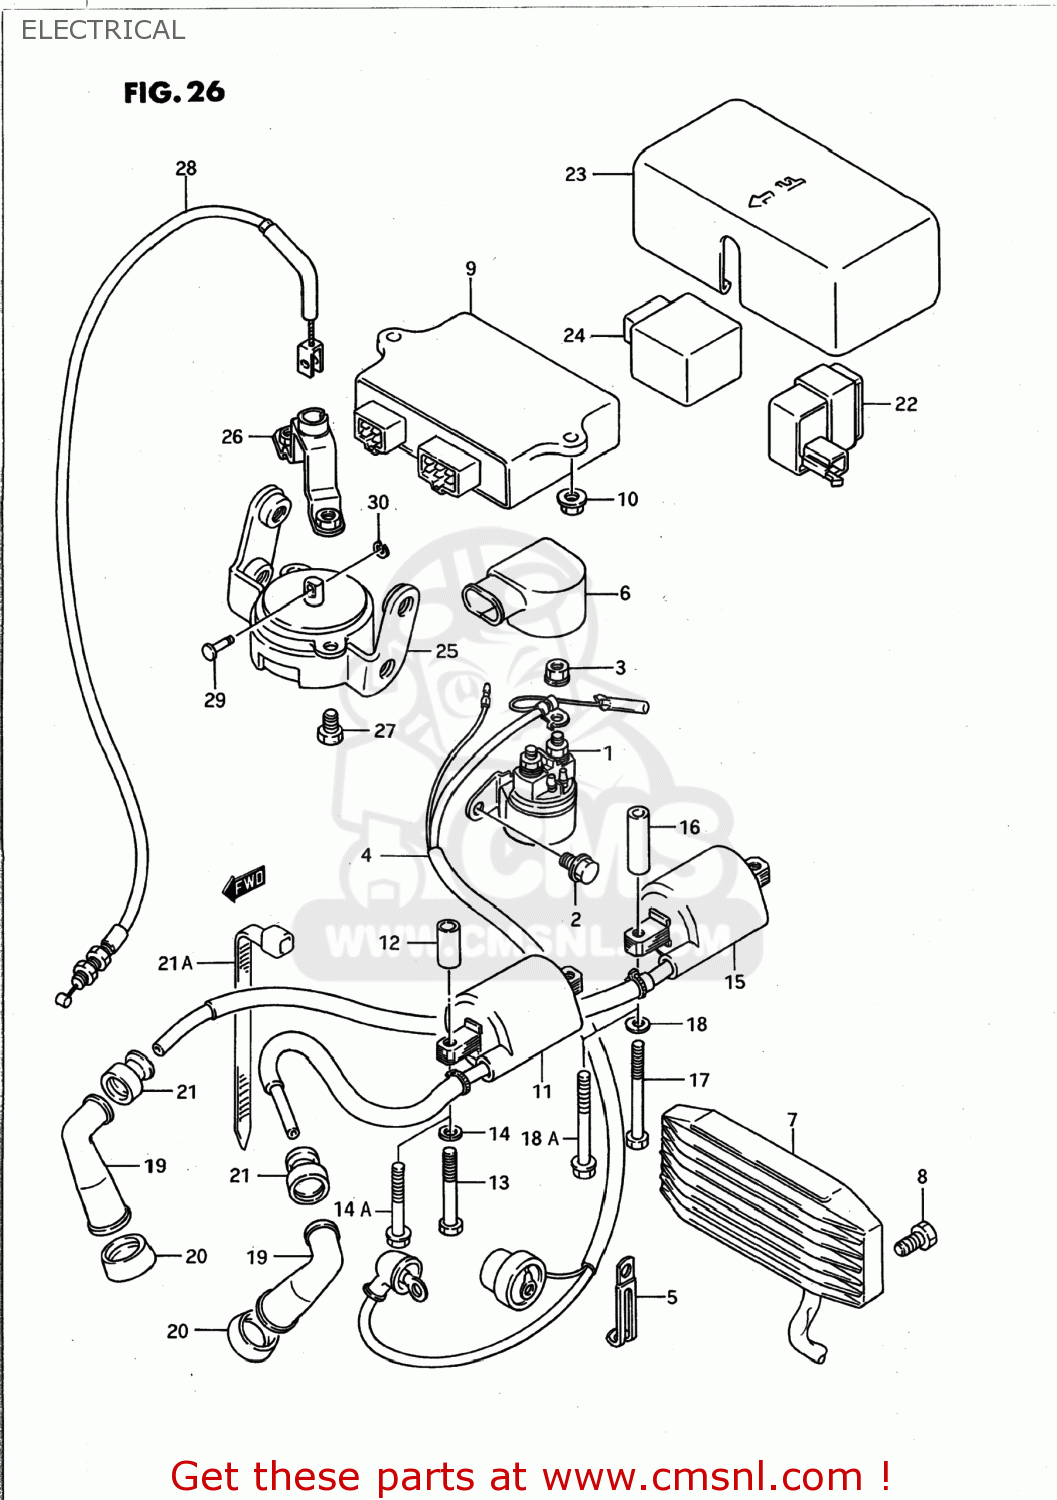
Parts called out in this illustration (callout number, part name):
1	RELAY ASSY,STARTING MOTOR
2	BOLT
3	NUT
4	WIRE,STARTER MOTOR LEAD
5	CLAMP L:35
6	CAP,BATTERY PLUS TERMINAL
7	RECTIFIER ASSY
8	BOLT
9	IGNITOR UNIT
10	NUT
11	COIL ASSY,IGNITION RR
12	SPACER(6.4X10X22)
13	BOLT
14	LOCK WASHER
14A	BOLT
15	COIL ASSY,IGNITION
16	SPACER(6.4X10X32)
17	BOLT
18	LOCK WASHER
18A	BOLT
19	CAP,SPARK PLUG
20	SEAL,SPARK PLUG CAP
21	SEAL,HIGH TENSION CORD
21A	CLAMP(L:125)
22	RELAY ASSY,FUEL CUT
23	COVER,RELAY
24	CONTROL UNIT,DECOMP
25	SOLENOID ASSY,DECOMP
26	BRACKET,DECOMP SOLENOID
27	BOLT
28	CABLE ASSEMBLY,DECOMPRESSION
29	PIN(4X12.5)
30	E RING
